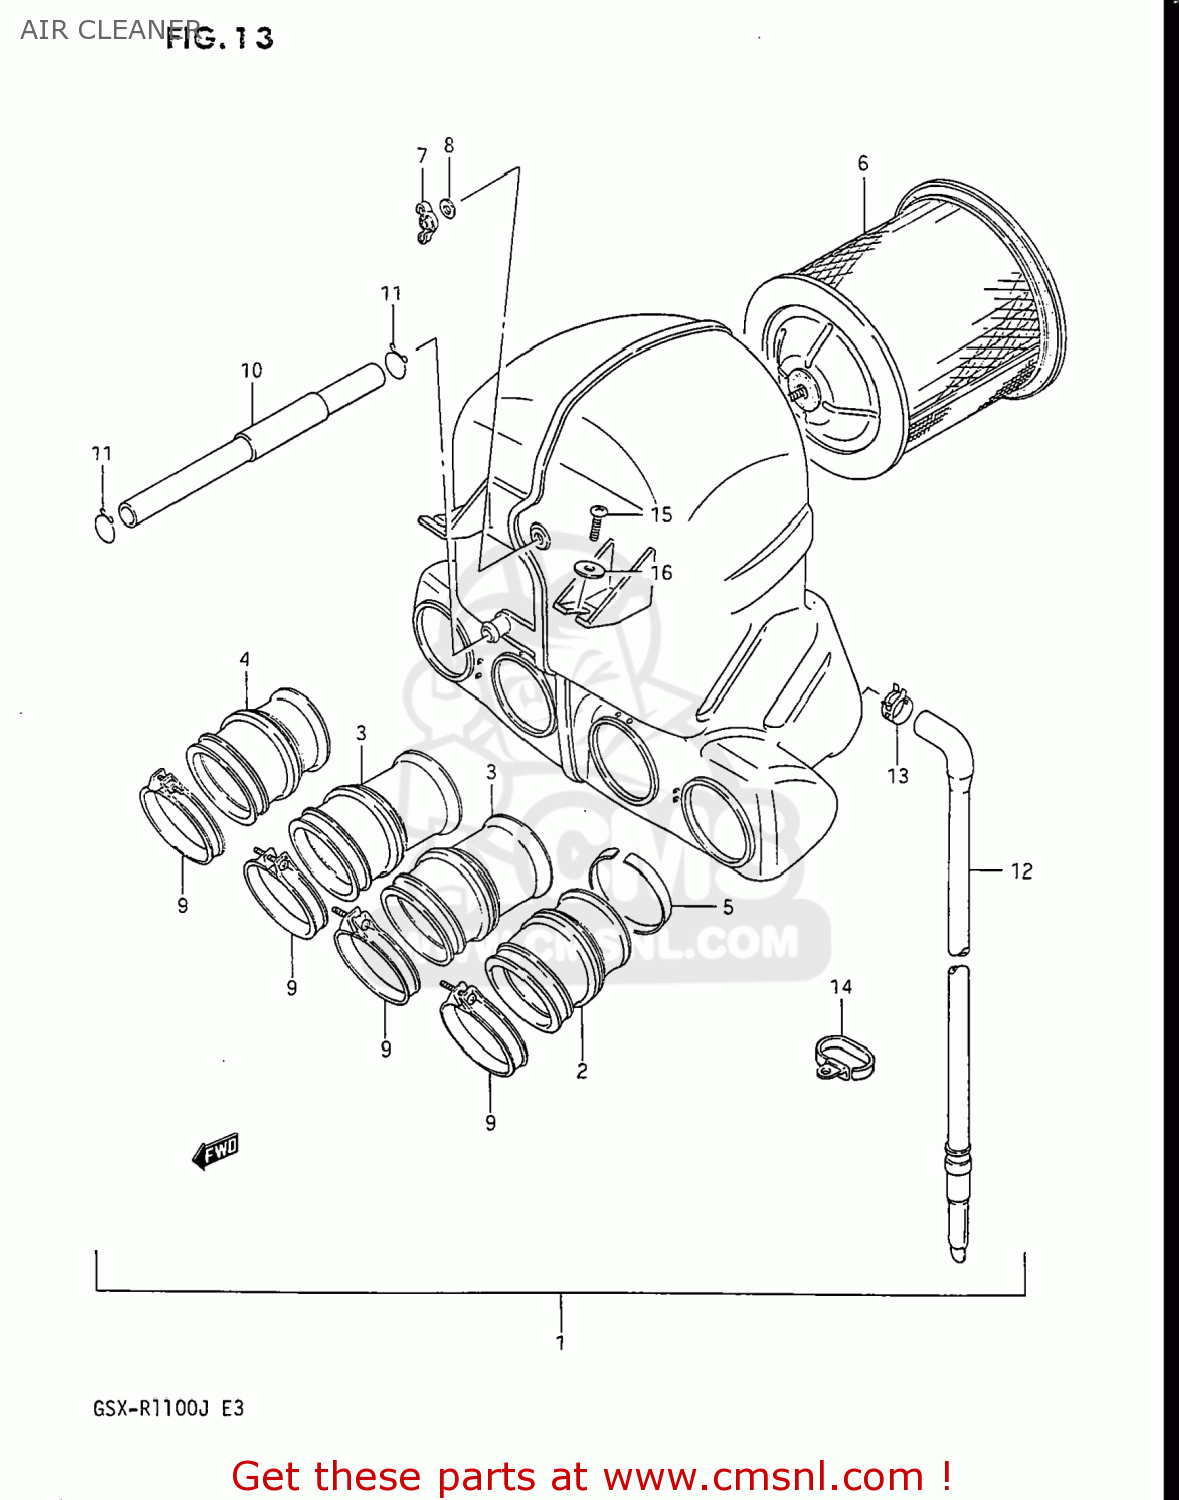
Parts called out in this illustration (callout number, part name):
1	CLEANER ASSEMBLY,AIR
2	TUBE,OUTLET,L
3	TUBE,OUTLET MIDDLE,L/R
4	TUBE,OUTLET,R
5	RING
6	FILTER
7	NUT, WING
8	WASHER 5MM
9	CLAMP
10	TUBE,BREATHER
11	CLIP
12	DRAIN TUBE
13	CLIP
14	CLAMP,AIR CLEANER DRAIN TUBE
15	SCREW
16	WASHER
